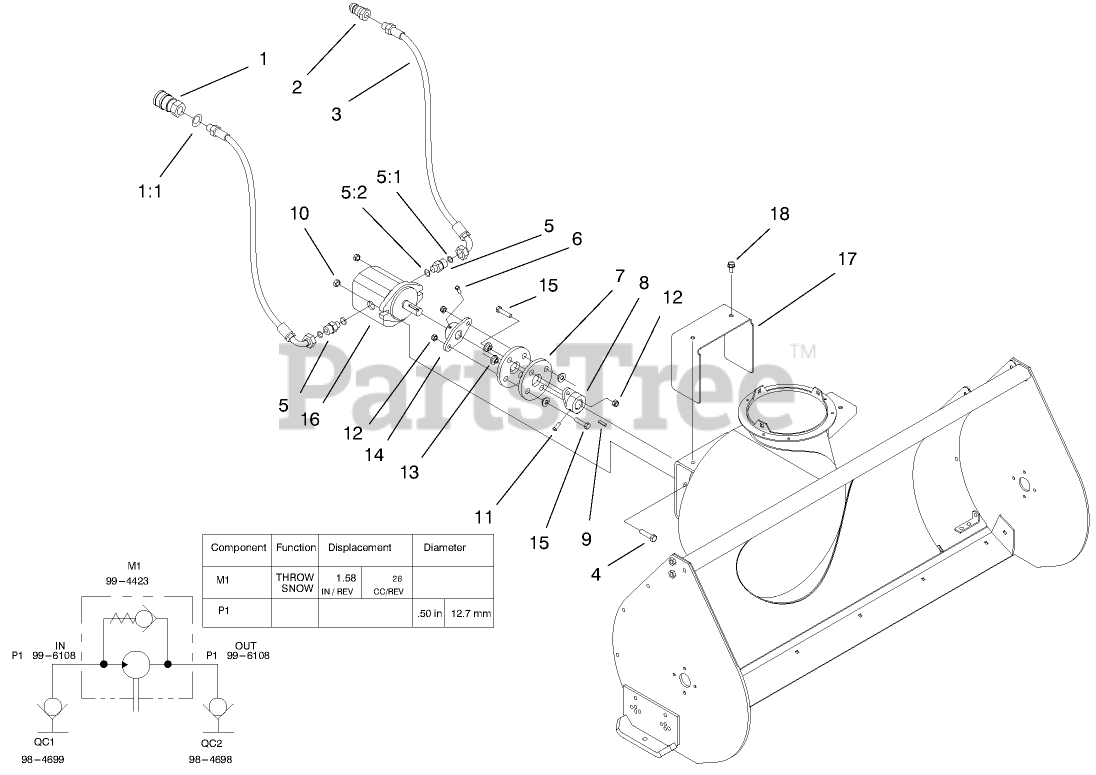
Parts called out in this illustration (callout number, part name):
1	FEMALE-DISCONNECT, QUICK
1:1	SEAL KIT
2	MALE-DISCONNECT, QUICK
3	HOSE-HYD
4	SCREW-HH
5	FITTING-STRAIGHT
5:1	O-RING
5:2	O-RING
6	SCREW-SET
7	COUPLING-RUBBER
8	HUB-COUPLER
9	KEY
10	NUT-LOCK, NI
11	SCREW-SET, SQH
12	NUT-LOCK, NI
13	SPACER
14	HUB-PUMP
15	SCREW-HH
16	MOTOR-HYDRAULIC
17	SHIELD-MOTOR
18	SCREW-HWHTF
